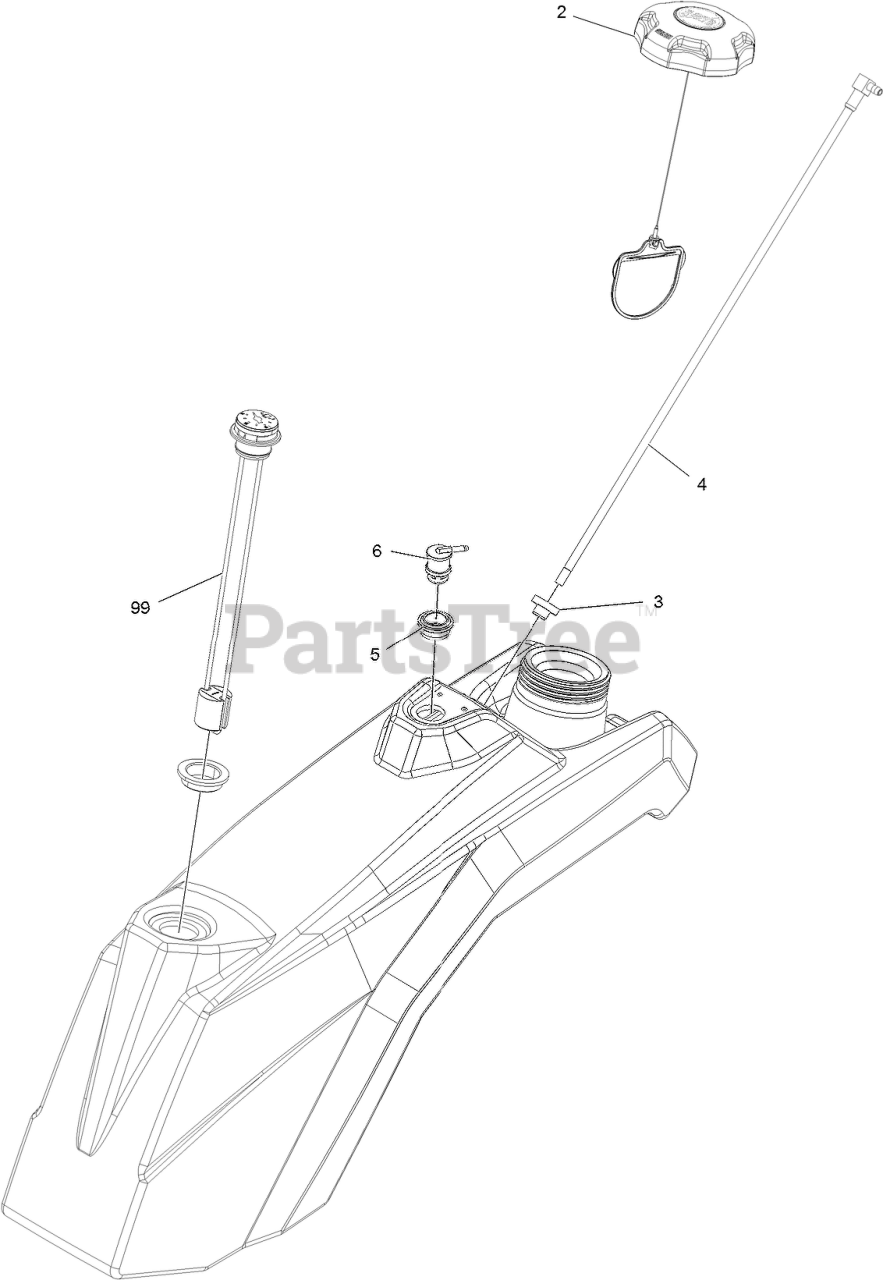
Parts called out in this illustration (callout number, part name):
2	CAP-FUEL, RATCHETING
3	BUSHING
4	STRAW, FUEL, SHORT
5	GROMMET
6	VALVE-VENT, FUEL
99	KIT, FUEL GAUGE
